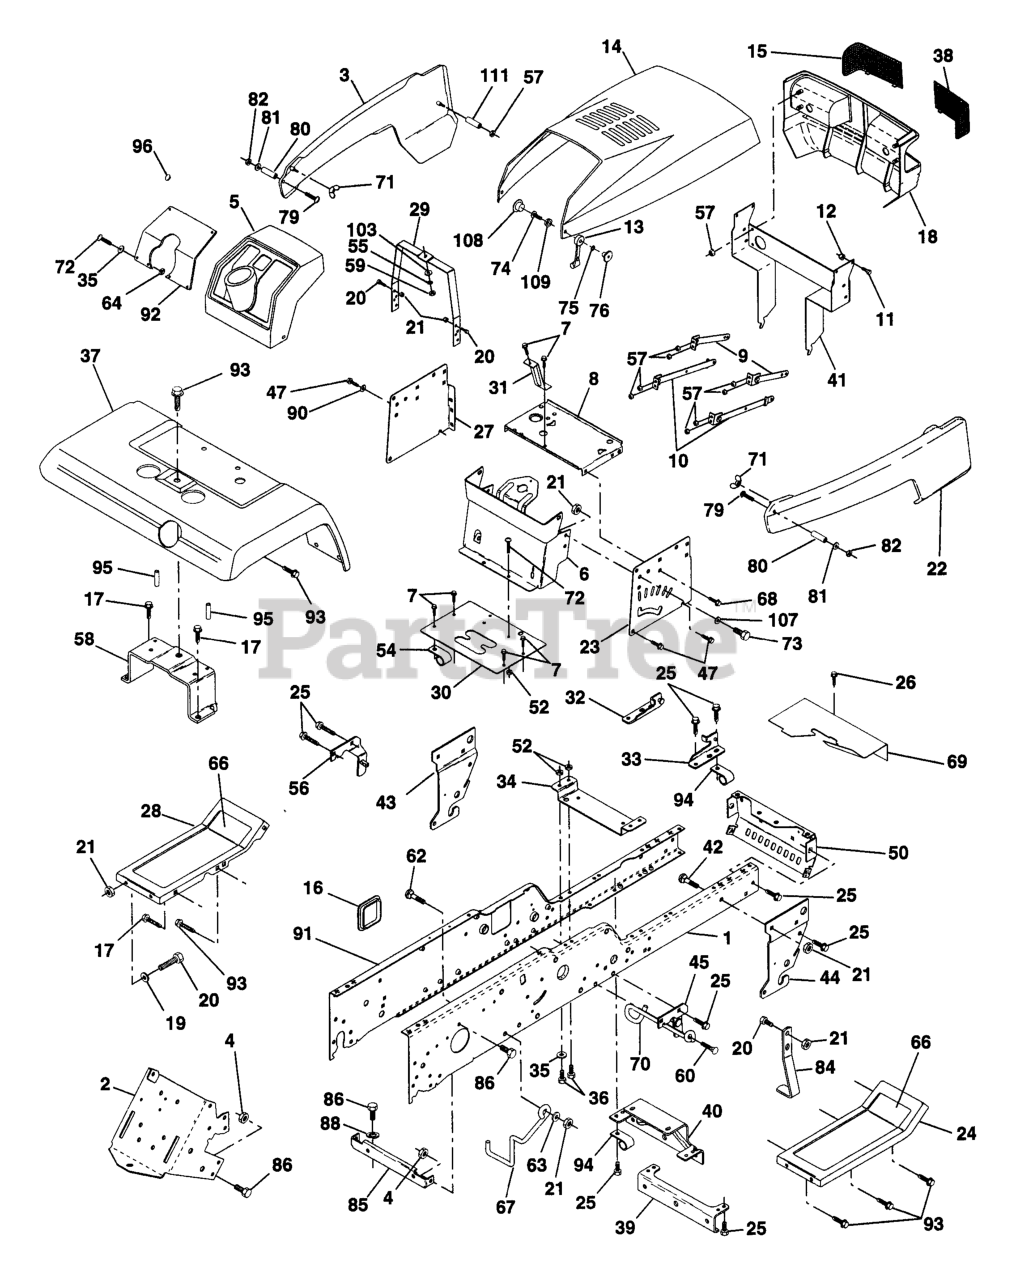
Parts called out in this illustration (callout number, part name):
1	FRAME RAIL RH
2	DRAWBAR-GT
3	SIDE PANEL ASSY LH
4	Nut, Lock Hex 7/16 Unc
6	Dash Asm., Lower
7	SCREW
8	BATTERY SUPPORT
9	STRAP ASSY LT
10	STRAP ASSY LT
11	BOLT T
12	LOCKNUT.NYLOC.1/4-20
13	LATCH.HOOD.
14	HOOD
15	LENS LH
16	COVER ACCESS
17	SCREW
18	GRILL COMPLETE
19	WASHER
20	BOLT
21	NUT
22	SIDE PANEL ASSY RH
23	PANEL, DASH RH
24	PAD,SPACER
25	SCREW
26	SCREW.THDROL.5/16-18X3/4.TTY
27	PANEL, DASH LH
28	ROLL PIN NLA
29	SUPPORT ASS'Y
30	Saddle, Slkscr Vgt
31	STEERING SUPPORT BRACE
32	FRAME PIVOT BRKT ASSY LH
33	FRAME PIVOT BRKT ASSY RH
34	Bracket, Engine Support Rear
35	WASHER
36	BOLT.FIN.HEX.5/16-18X3/4
37	FENDER
38	LENS RH
39	FRONT AXLE BRACKET
40	Bracket, Support Axle/Engine
41	GRILL SUPPORT ASSY
42	BOLT D
43	FRONT SUSPENSION BRKT LH
44	FRONT SUSPENSION BRKT RH
45	CHASSIS BRKT
47	SCREW LT
50	CHASSIS BRKT
52	NUT.71038.31-18.HEX.NYLOCK
54	CLIP,INSULATOR
56	SUSPENSION BRKT LH
58	FENDER BRKT
59	NUT
60	SCREW
62	BOLT D
63	WASHER
64	NUT
66	PAD FOOTREST T
67	BELT GUIDE
68	Screw, Thdrol 5/16-18 x 1/2
69	HEAT SHIELD
70	BELT GUIDE
71	WING NUT
72	Screw, Mach Trhd 5/16-18 x 3/4
73	BOLT
74	SCREW
75	LOCKWASHER #10
76	WELDNUT
79	RP SCREW
82	NUT **
84	Stop, Over Center Mower
85	BRKT SUPPORT GT
86	BOLT
88	LOCKWASHER
90	LOCKWASHER
91	FRAME RAIL LH
92	DASH PLATE
93	SCREW LT
95	NUT-PUSH YT
96	PLUG-DASH T
103	LOCKWASHER
107	WASHER
108	SNAP CAP LT
111	SPACER NLA
